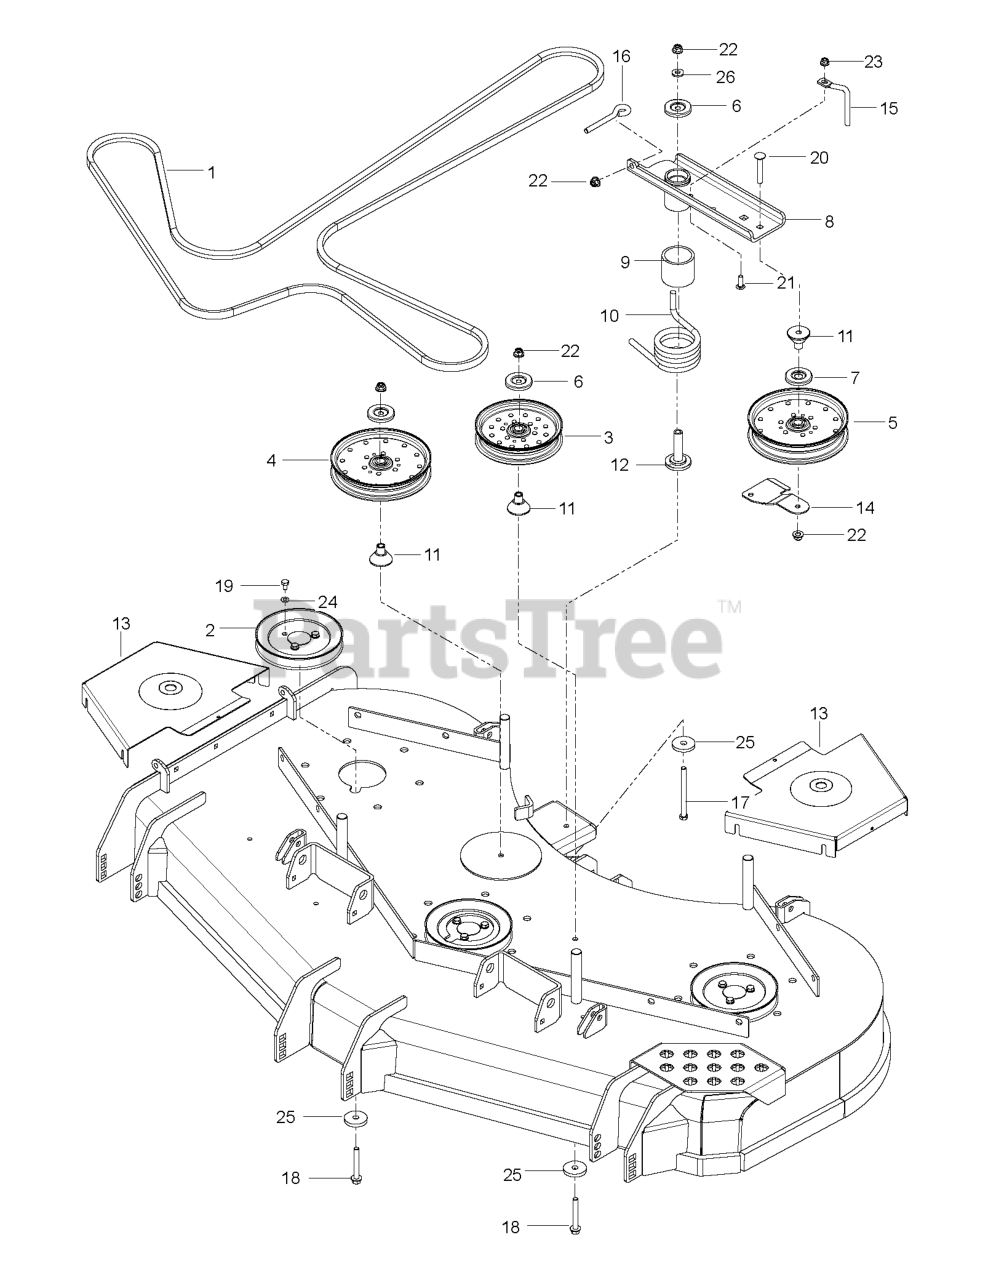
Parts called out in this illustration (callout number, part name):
1	BELT 5V 176.00
2	PULLEY - 6.57
3	PULLEY - 7" NARROW
4	PULLEY IDLER, 6" NARROW
5	PULLEY - IDLER 7"
6	DUST SHIELD
7	SHIELD, DUST
8	ASSY, IDLER ARM, PZ
9	SPACER, IDLER PIVOT
10	SPRING, TORSION, IDLER
11	BEARING, IDLER ARM
12	BEARING, IDLER PIVOT
13	SHIELD BELT - 60IN SNAPPER RED
14	BELT.GUIDE.BLACK
15	BELT KEEPER
16	EYE BOLT, 3/8 X 4"
17	HCS 3/8-16 X 4-1/2 GR 8 ZD
18	HHFS 3/8-16 X 2-3/4 GR5 ZD
19	HCS 5/16-18 X 1/2 GR 5 ZD
20	CARRIAGE BOLT 3/8-16 X
21	BOLT CRT
22	NUT 3/8-16 HEX FLG NYLOC ZD
23	5/16-18 NYLOC FLANGE NUT
24	WASH 5/16 DISC SPRING ZD
25	SPINDLE WASHER
26	WASHER, 3/8 THICK
